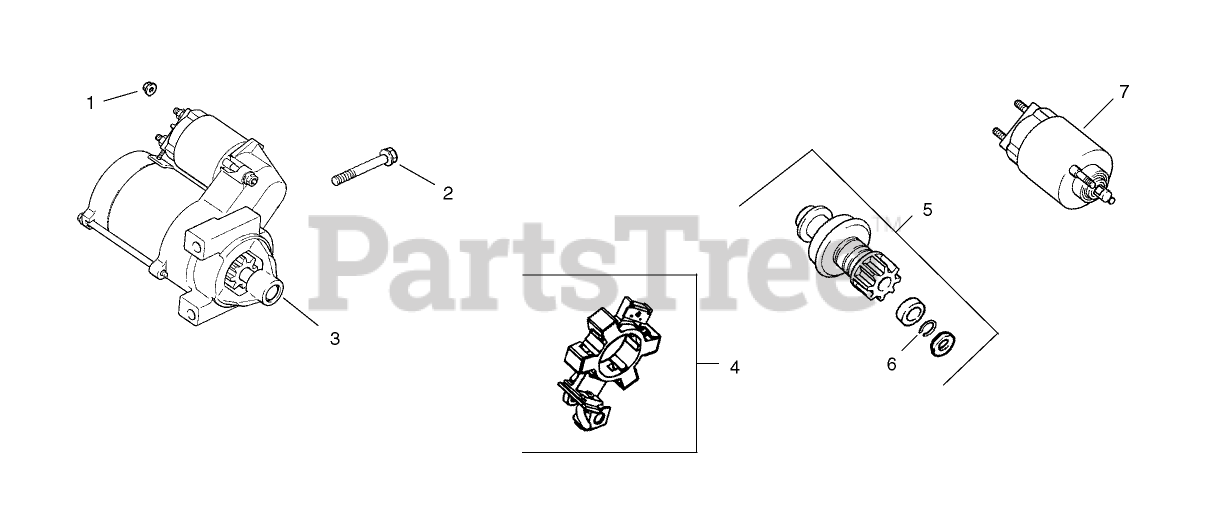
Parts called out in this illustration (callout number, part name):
1	NUT-FLANGE (M8X1.25)
2	SCREW-FLG (M8X1.25X80)
3	Starter assembly(Includes 4-7)
4	BRUSH HOLDER KIT
5	Kit, pinion drive (Includes 6)
6	RING-RETAINING
7	Solenoid Kit
